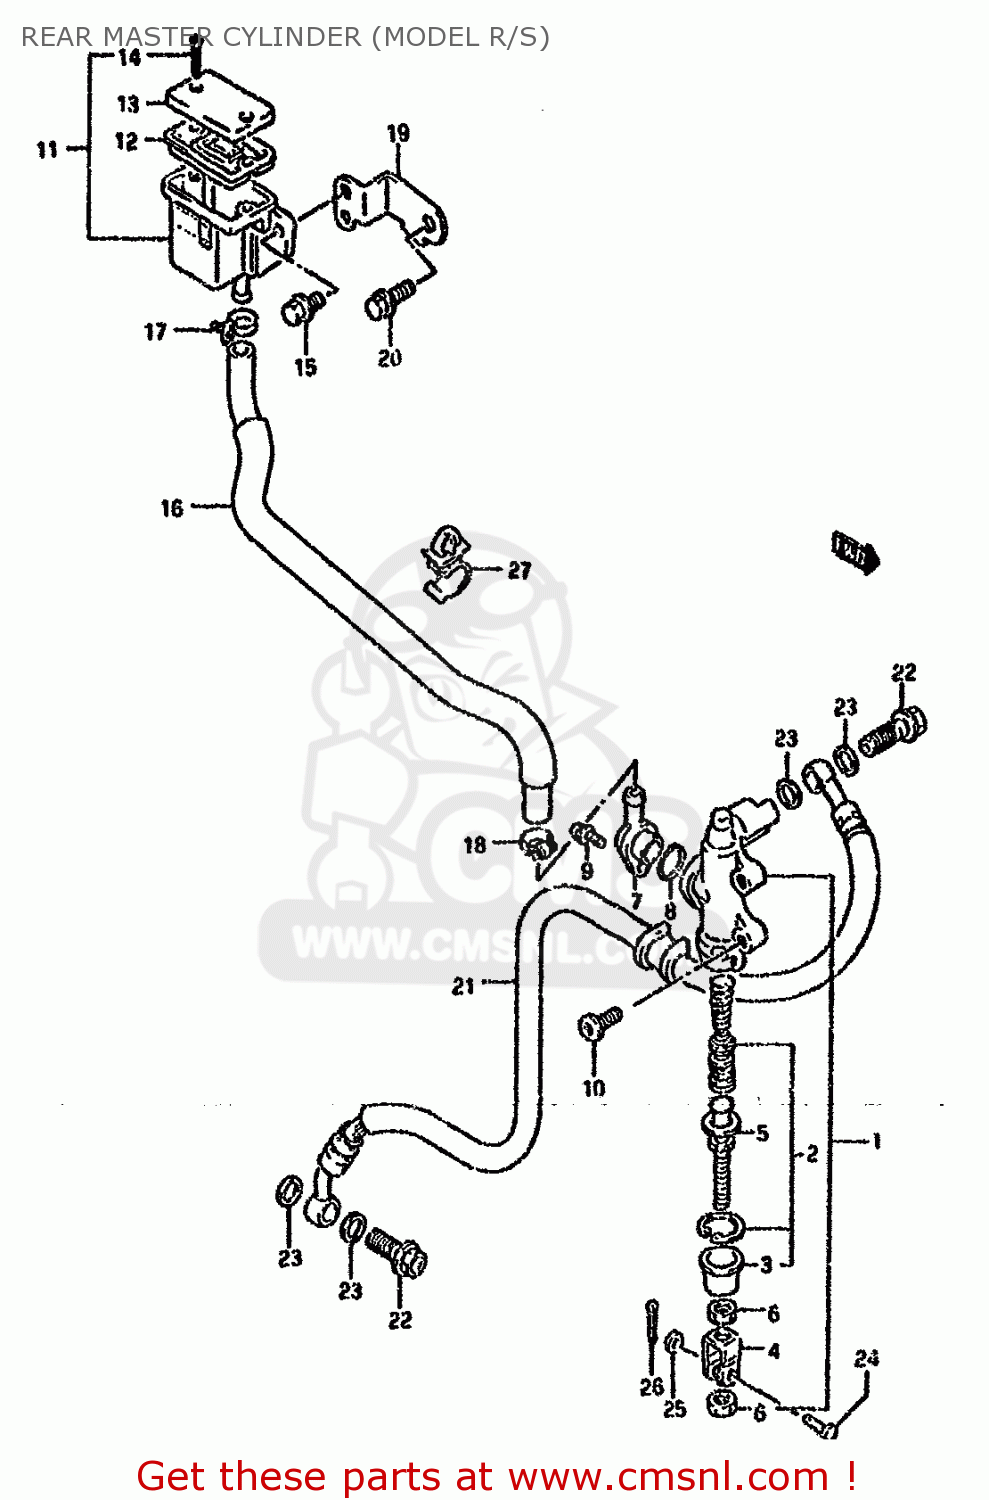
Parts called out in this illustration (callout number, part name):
1	CYLINDER ASSEMBLY,REAR MASTER
2	PISTON/CUP SET
3	BOOT
4	YOKE
5	ROD,PUSH
6	NUT
7	CONNECTOR
8	O RING
9	SCREW
10	SCREW(8X22)
11	TANK ASSY,RESERVOIR
12	DIAPHRAGM
13	CAP
14	SCREW
15	BOLT
16	HOSE,RESERVOIR TANK
17	CLAMP
18	CLAMP
19	PLATE,RESERVOIR TANK
20	BOLT
21	HOSE,RR BRAKE
22	BOLT UNION
23	WASHER(10X15X1.5)
24	PIN
25	WASHER
26	PIN
27	CLAMP
